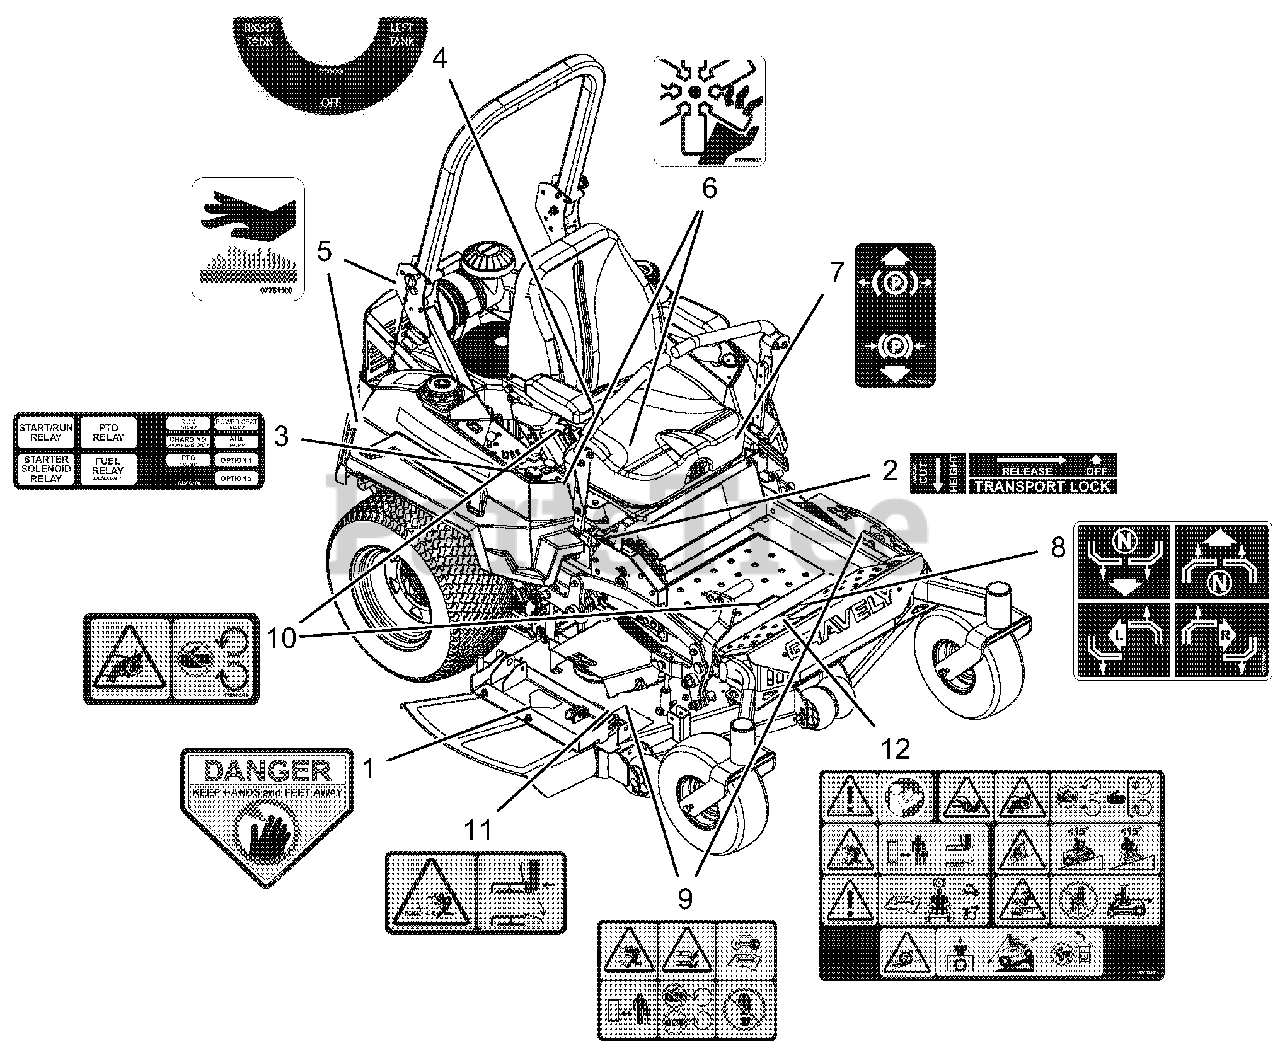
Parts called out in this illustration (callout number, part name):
1	DECAL, DANGER
2	DECAL, TRANSPORT LOCK INSTR
3	DECAL, FUSE BOX
4	DECAL- FUEL CONTROL VALVE
5	DECAL, HOT SURFACE
6	DECAL, DANGER FAN
7	DECAL, PARKING BRAKE LEVER
8	DECAL, INSTRUCTIONAL-STEERING
9	DECAL, SAFETY - MOWER DECK
10	DECAL, SAFETY - GUARDING
11	DECAL, SAFETY - DECK GUARDING
12	DECAL, MAIN SAFETY
